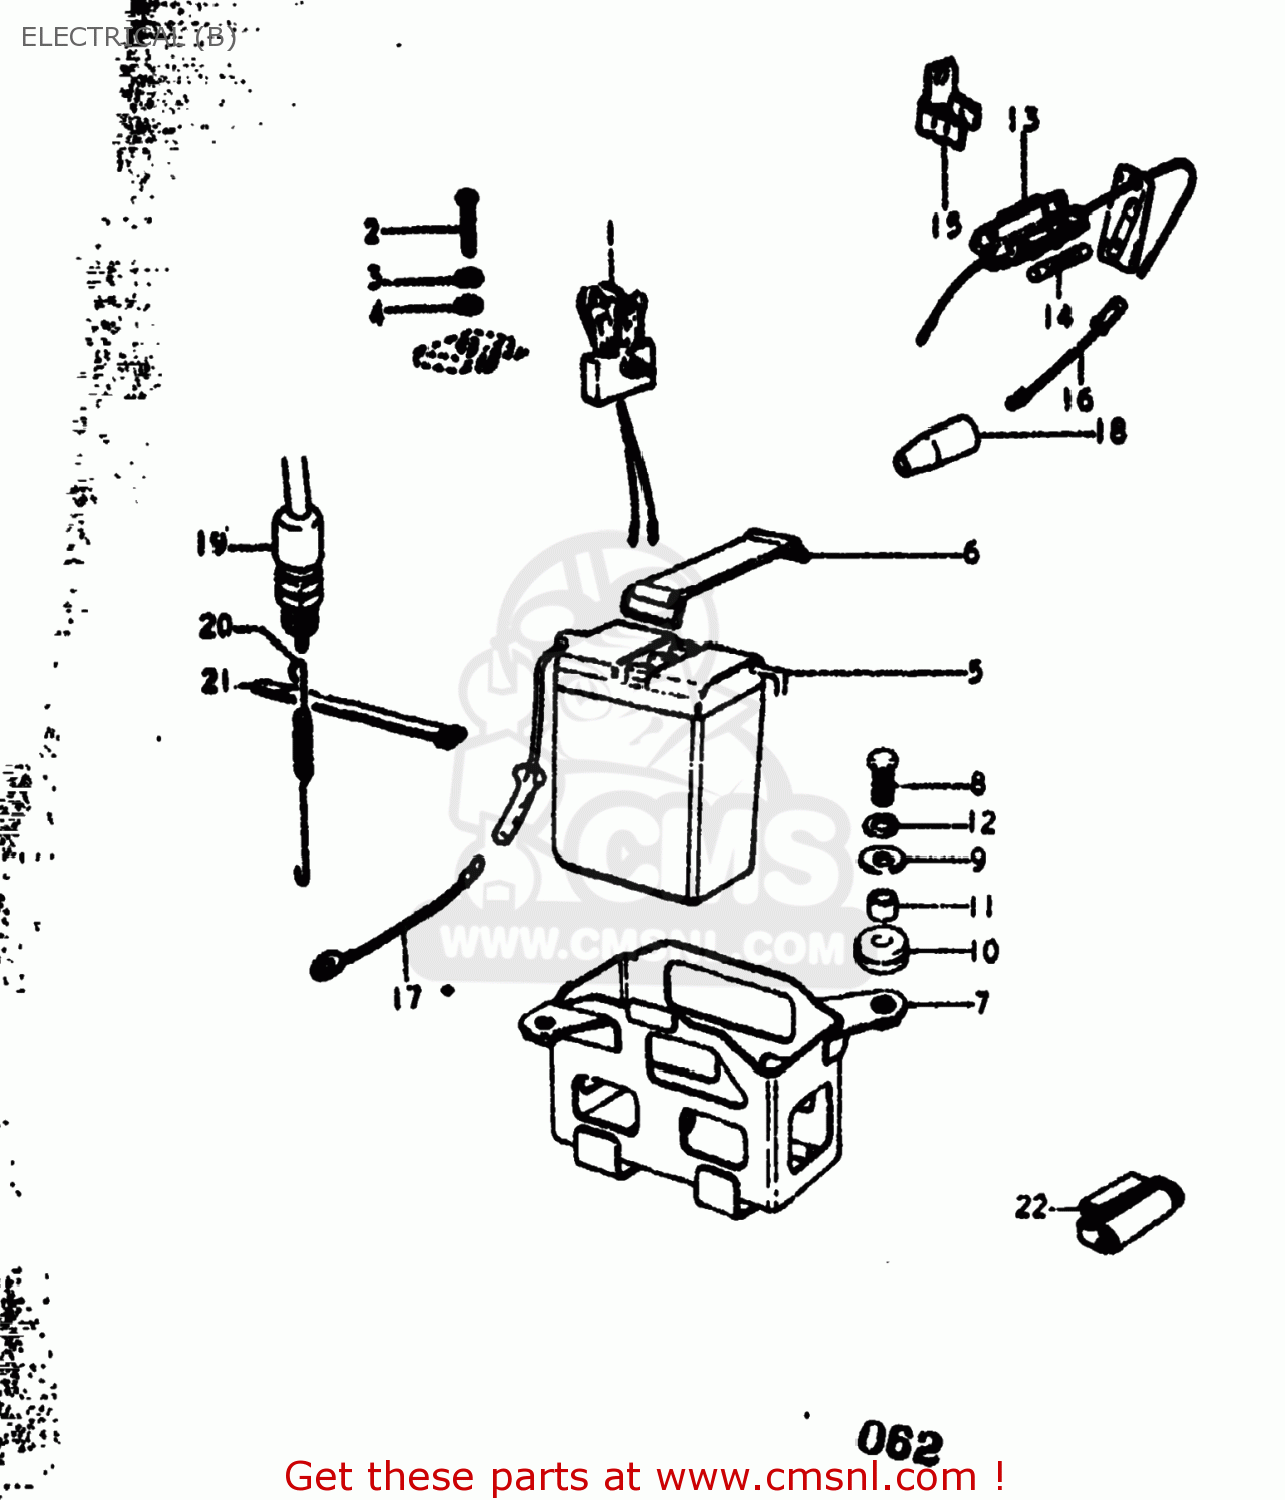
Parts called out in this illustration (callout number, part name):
1	RECTIFIER ASSEMBLY
2	SCREW
3	LOCK WASHER
4	WASHER
5	BATTERY(6N4B-2A,6V4.2AH)
6	BAND
7	HOLDER,BATTERY
8	BOLT
9	WASHER (6.5X20X1.2)
10	CUSHION
11	SPACER (7X9X7)
12	LOCK WASHER
13	BOX ASSEMBLY,FUSE
14	FUSE(15A)
15	HOLDER,FUSE CASE
17	LEAD WIRE
18	SEAL,DUST(10X17X45)
19	SWITCH,BRAKE LAMP
20	SPRING
21	CLAMP
22	REGISTER
